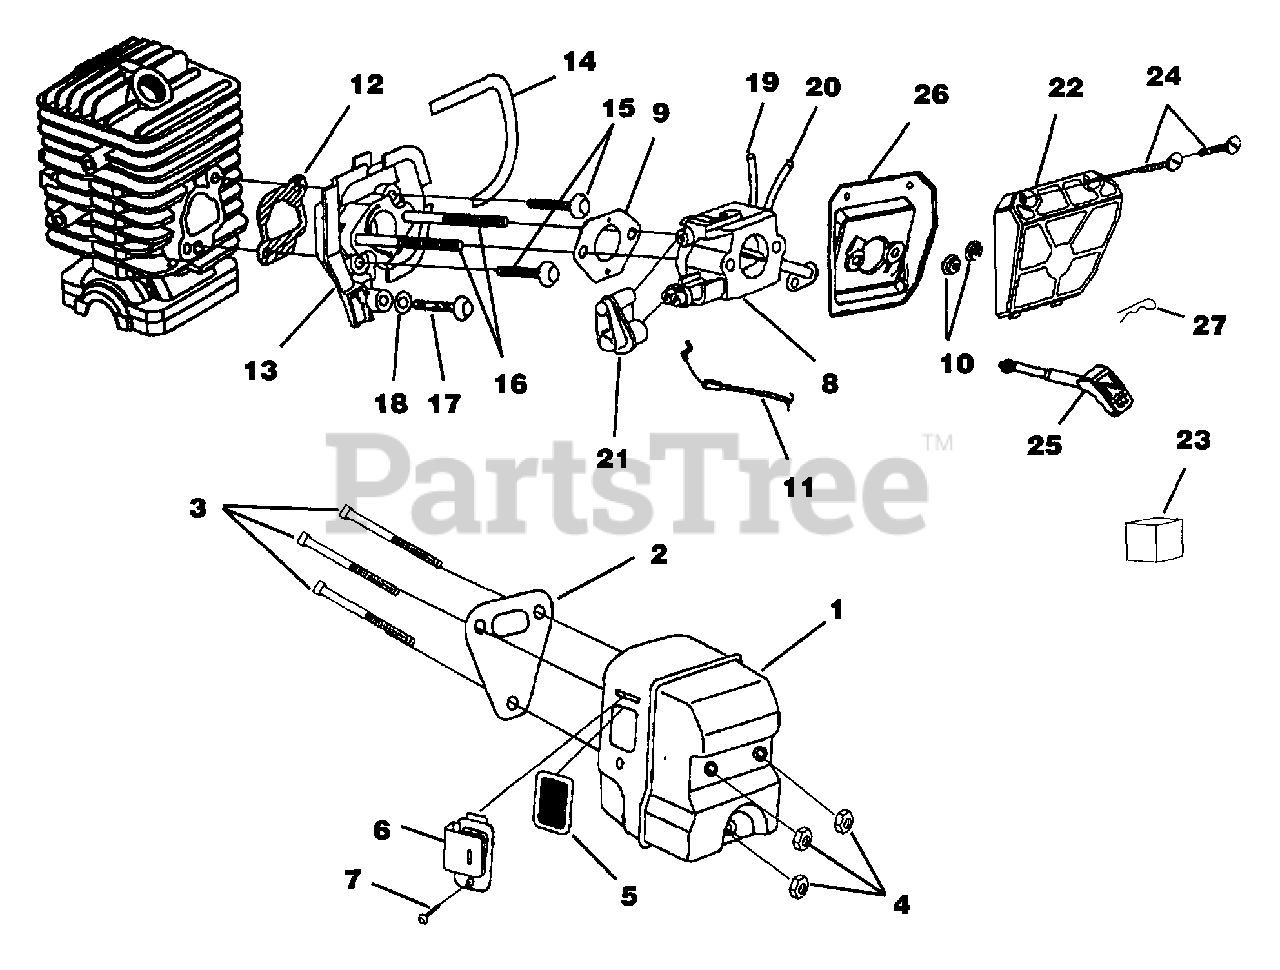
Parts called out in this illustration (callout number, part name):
1	Muffler Kit
2	Muffler Gasket
3	Screw-Square Hd.
4	Nut-Locking Hex (10-32)
5	Screen, Spark
6	Deflector, Muffler
7	Screw
8	Carburetor Kit
9	Carburetor Gasket
10	Flange Nut (10-24)
11	Throttle Cable
12	Gasket, Heat Dam
13	Heat Dam
14	Seal, Heat Dam
15	Screw, Truss Hd. Taptite (10-24 x 7/8")
16	Screw, Carburetor
17	Screw, Thread Form (10-14 x 1/2")
18	Washer, Retaining
19	Fuel Line (Tank to Carburetor 8 1/2")
20	Fuel Line (Carburetor to Purge Bulb 4")
21	Carburetor Grommet
22	Air Filter Cover
23	Pre Filter (In engine housing)
24	Screw-Slotted Pan Hd. (8-16 x 5/8")
25	Rod, Choke
26	Air Filter Plate
27	Spring Clip (Choke Rod)
